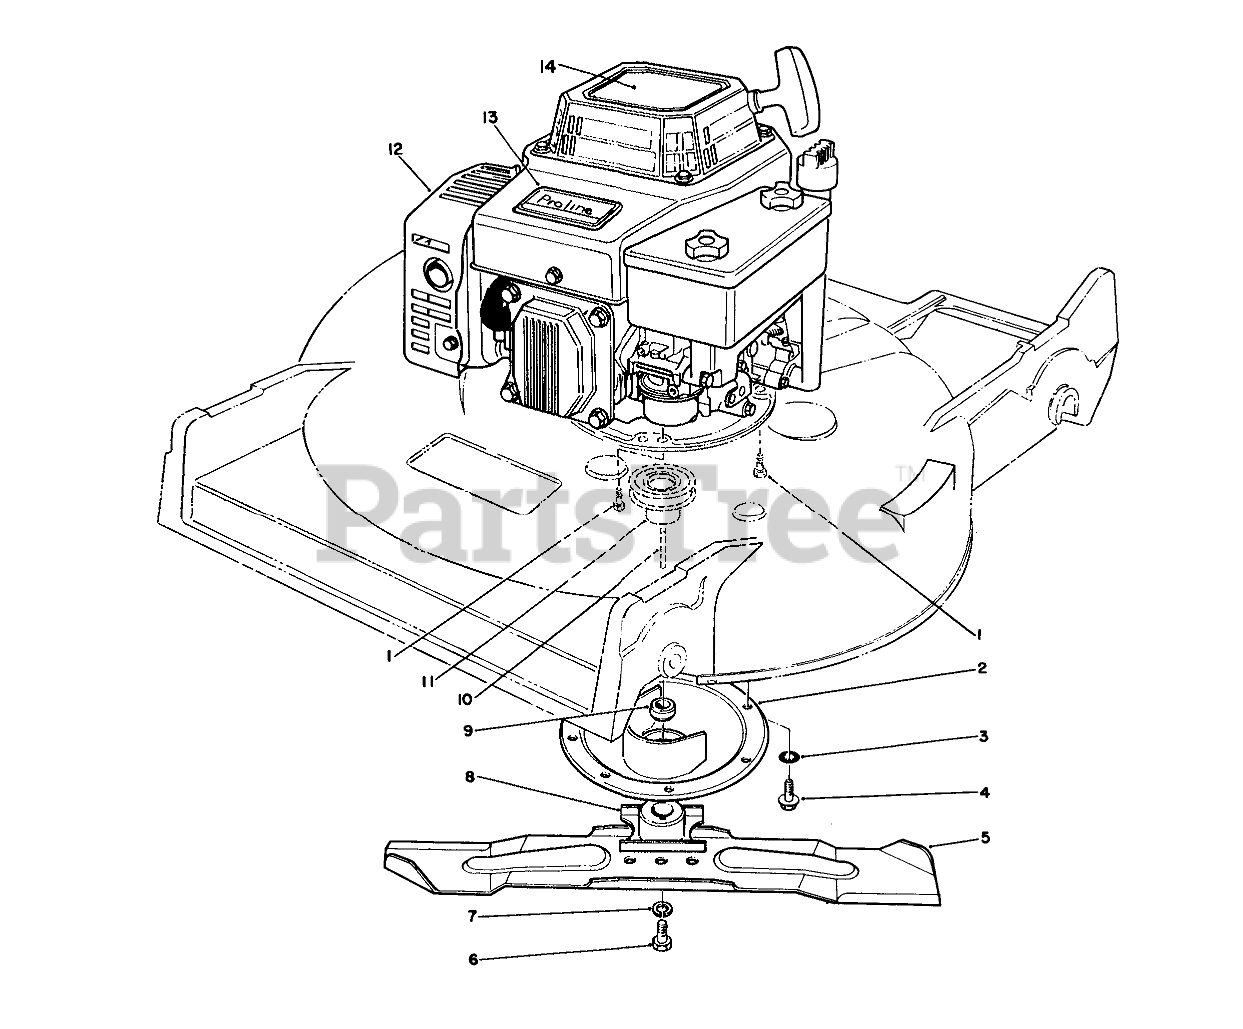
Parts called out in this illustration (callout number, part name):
1	SCREW-HWHTF
2	PROTECTOR-CRANKSHAFT
3	WASHER-LOCK, INTERNAL
4	SCREW-HWHTF
5	Key
6	SCREW-BLADE
7	WASHER-LOCK
8	RETAINER-BLADE
9	SPACER-BLADE RETAINER
10	KEY-SQUARE
11	PULLEY-DRIVER
12	Engine
13	DECAL - PROLINE
14	DECAL - RECOIL
